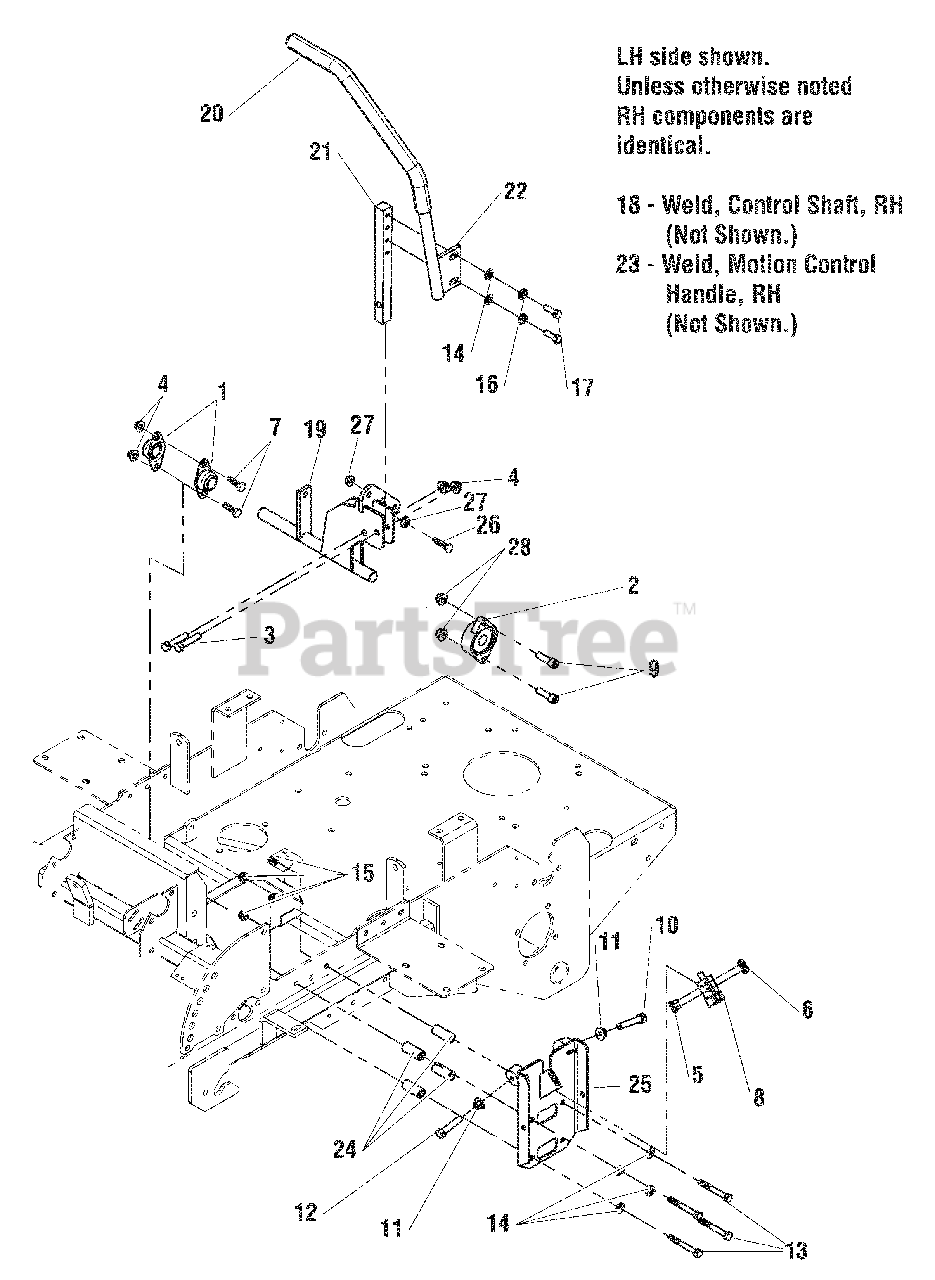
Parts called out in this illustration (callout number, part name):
1	BEARING, BRONZE FLANGE, 3/4
2	BEARING, FLANGE
3	BOLT, 3/8-16 X 1-3/4" GD5 CZ
4	NUT, 3/8-16 HEX NYLOCK FLANGE
5	SCREW, #10-24 X 1/2 ROUND PHILLIPS
6	NUT, #10-24 HEX
7	BOLT, 3/8-16 X 1" GD5 CZ
8	SWITCH, PLUNGER, N.O./N.C.
9	BOLT, 3/8-16 X 1-1/4 SHCS (SOCKET HEAD)
10	BOLT, 5/16-18 X 2 GD5 TFL
11	NUT, 5/16-18 HEX SERRATED FLANGE (LARGE)
12	BOLT, 5/16-18 X 1-3/4 GD5 TFL
13	BOLT, 5/16-18 X 2-1/2 GD5 YZ
14	WASHER, 5/16" SAE
15	NUT, 5/16-18 HEX NYLOCK FLANGE
16	WASHER, 5/16 LOCK YZ
17	BOLT, 5/16-18 X 1 GD5 YZ
18	WELD, CONTROL SHAFT - RH
19	WELD, CONTROL SHAFT - LH
20	GRIP, FOAM, 3/4 ID, 16 LONG
21	MOUNT, CONTROL ARM
22	WELD, HANDLE MOTION CONTROL-LH
23	WELD, HANDLE MOTION CONTROL-RH
24	SPACER, .39 X .63 X 1.50
25	WELD, PLATE, NEUTRAL
26	BOLT, 5/16-18 X 1 1/2 FLANGE
27	NUT, 5/16-18 HEX SERRATED FLANGE (LARGE)
28	NUT, 3/8-16 HEX NYLON LOCK
